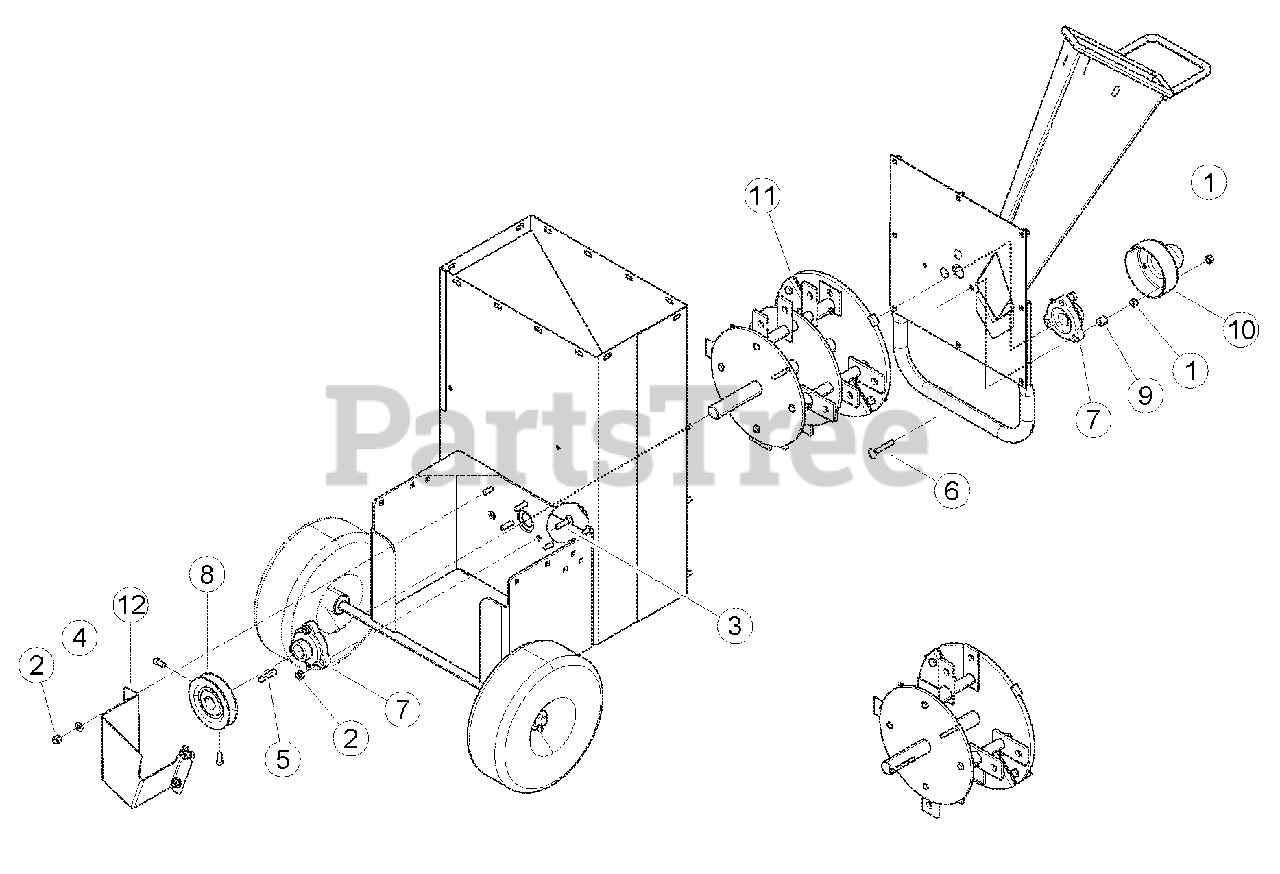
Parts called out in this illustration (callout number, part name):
1	NUT, 5/16 CENTERLOCK NC ZP
2	NUT, 5/16 NE NYLOCK ZP
3	BOLT, 5/16 X 1-1/4 CRG GR5 ZP
4	WASHER, 5/16 SAE FLAT ZP
5	KEY, 1/4 SQUARE X 1-1/2 LONG PLAIN
6	BOLT, 5/16 X 2 CRG GR5 NC ZP
7	BEARING, 1" FLUSHMOUNT CAST W/COLLAR
8	PULLEY, CAST 4" OD, 1"BORE, B GRV
9	SPACER, .54OD X .50" LG
10	CAP, ROTOR SHAFT END CAP
11	ASSEMBLY, WIDE ROTOR W/RECT KNIVES
11	ASSY, NAR. ROTOR-RECT KNIVES (SC3206 ONLY)
12	SHIELD, LOWER
